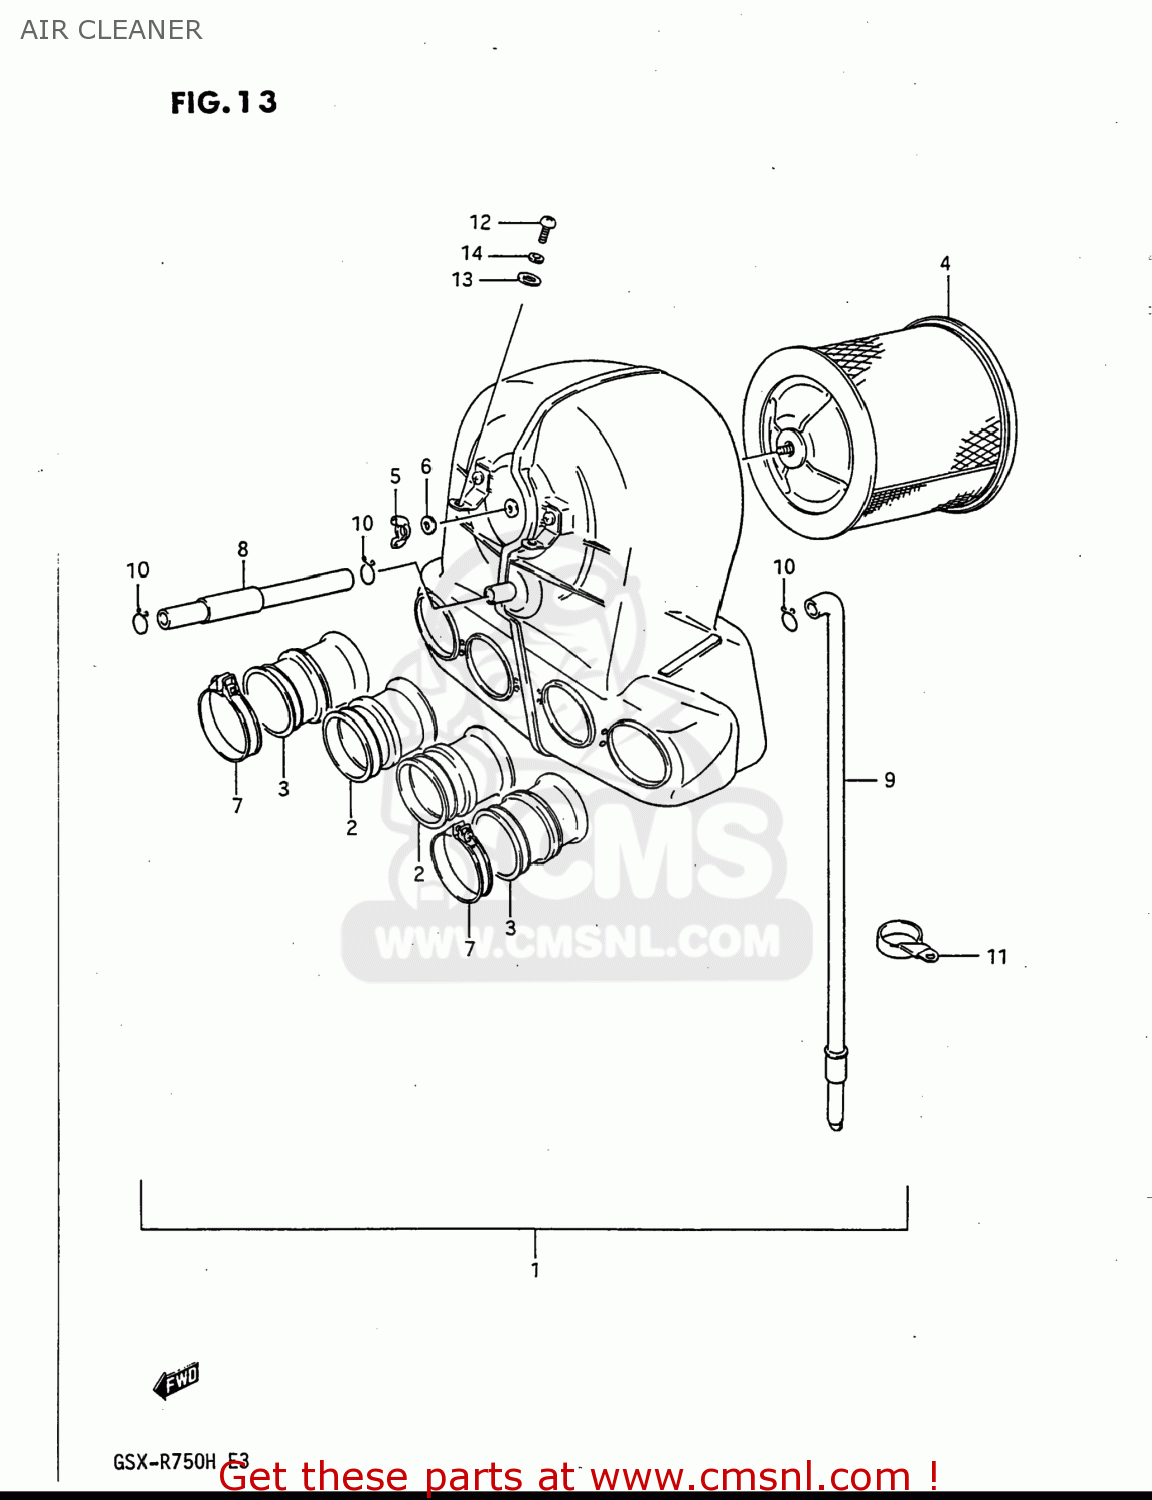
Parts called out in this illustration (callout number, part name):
1	CLEANER ASSY,AIR
2	TUBE,OUTLET NO.1
3	TUBE,OUTLET NO.2
4	FILTER ASSY
5	NUT, WING
6	WASHER 5MM
7	CLAMP
8	TUBE,BREATHER
9	DRAIN TUBE
10	CLIP
11	CLAMP,AIR CLEANER DRAIN TUBE
12	SCREW
13	WASHER(6.5X16X1.2)
14	WASHER,LOCK
